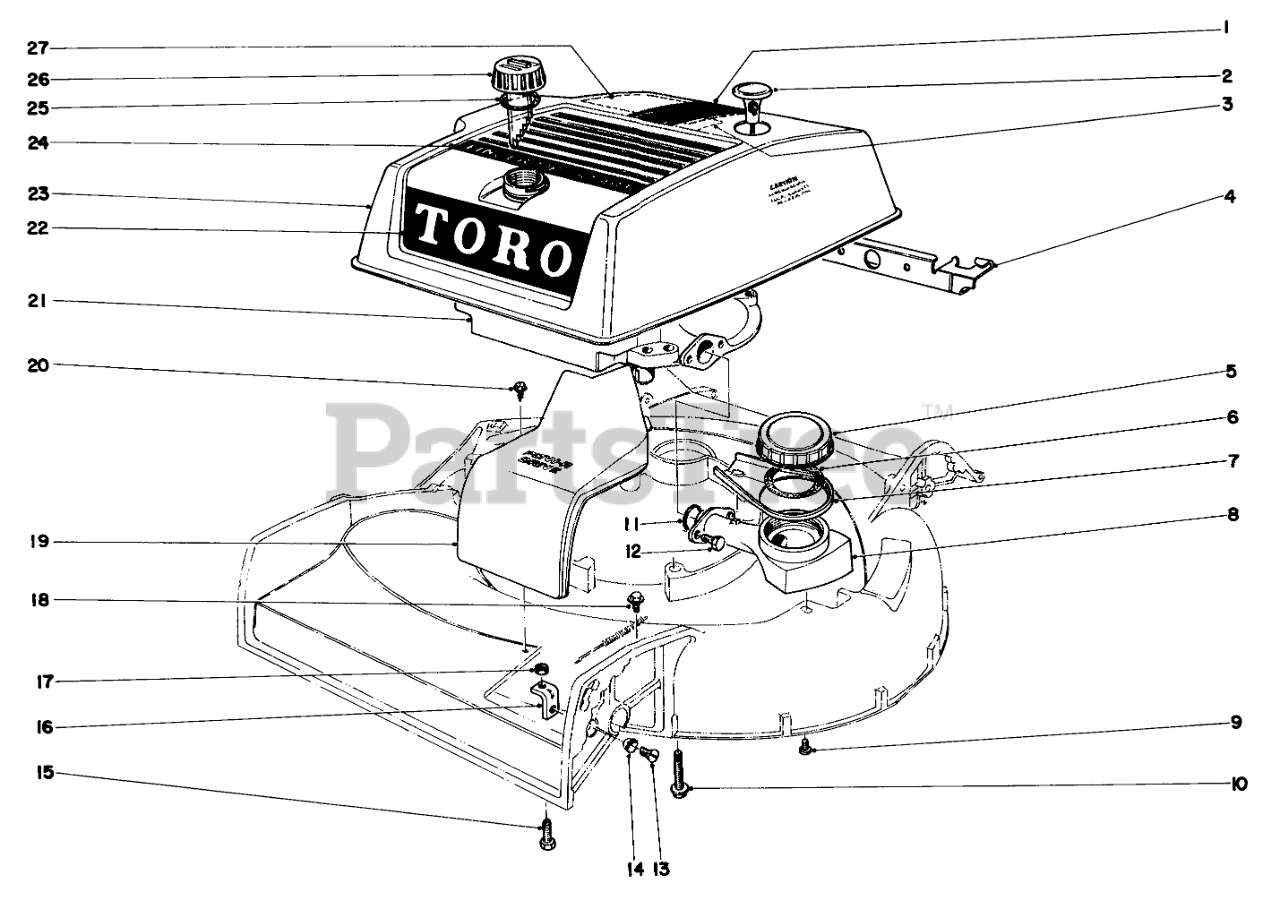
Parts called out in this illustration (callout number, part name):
1	Decal
2	Rope Handle
3	Decal Caution
4	Shroud Bracket
5	Oil Gauge Cap
6	VISUAL OILER GASKET
7	Spout
8	Oil Gauge
9	Screw
10	3/8-16 X 2-3/4 CAPSCR
11	O RING
12	SCREW-HH
14	Lockwasher
15	SCREW
16	ADJ BRACKET
17	NUT-JAM
18	Screw
19	Cover
20	SCREW-HWHTF
21	Engine
22	Decal-Toro
23	Engine Shroud
24	Decal
25	Gasket
26	Gas Cap (Incl. Ref. No. 25)
27	Decal-Maintenance
